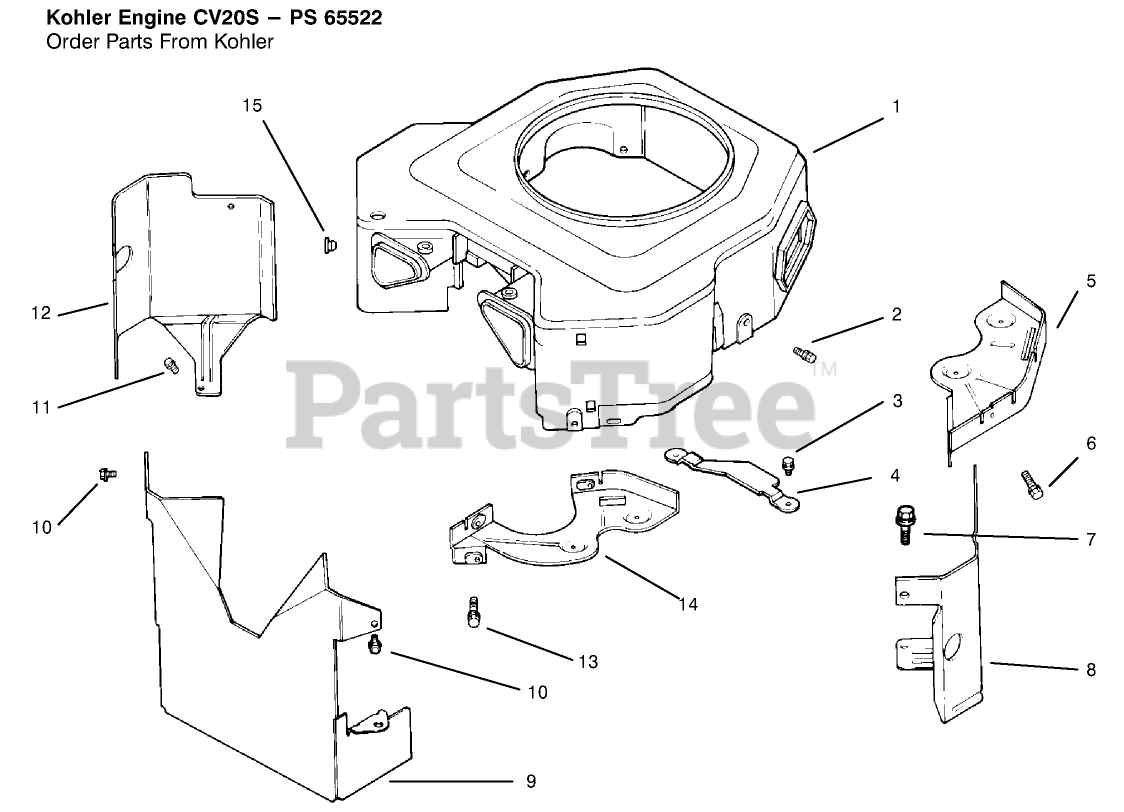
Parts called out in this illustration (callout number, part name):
1	Housing-Blower
3	Screw
4	Guard-Flywheel
5	Plate-Backing #2 Side
6	Screw
7	Screw
8	Baffle-Cylinder, #2
9	Baffle-Valley
10	Screw
11	Screw
12	Baffle-Cylinder #1 Side
14	Plate-Backing #1
15	Nut-Plastic
